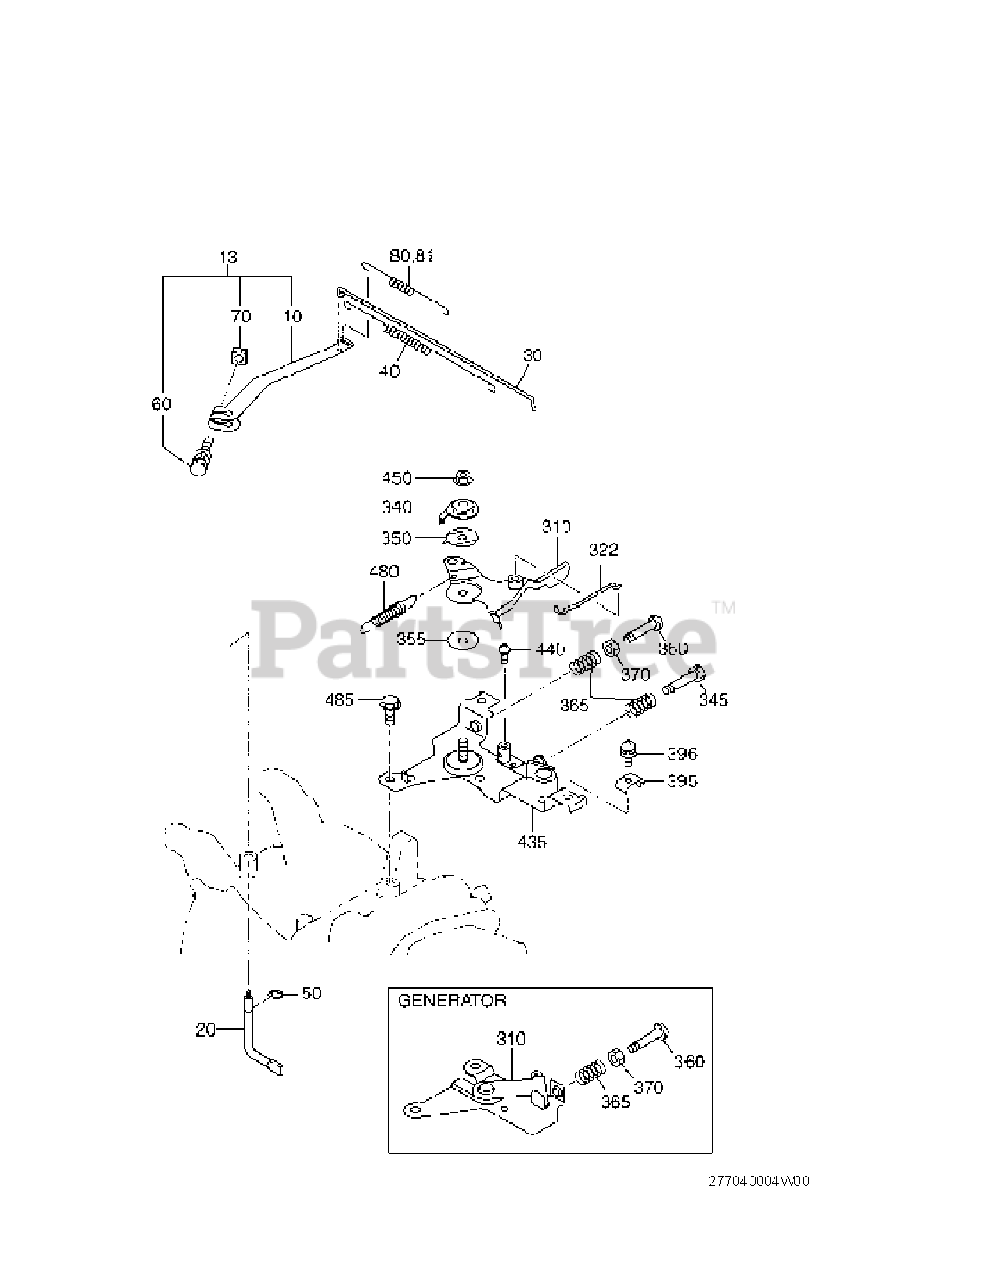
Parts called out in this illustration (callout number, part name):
13	GOVERNOR LEVER AY
20	GOVERNOR SHAFT
30	GOVERNOR ROD CP
60	BOLT AND WASHER AY
80	GOVERNOR SPRING
310	SPEED CONTROL LEVER
355	FRICTION WASHER
365	SPRING (ADJUST)
435	SPEED CONT.BRKT CP
